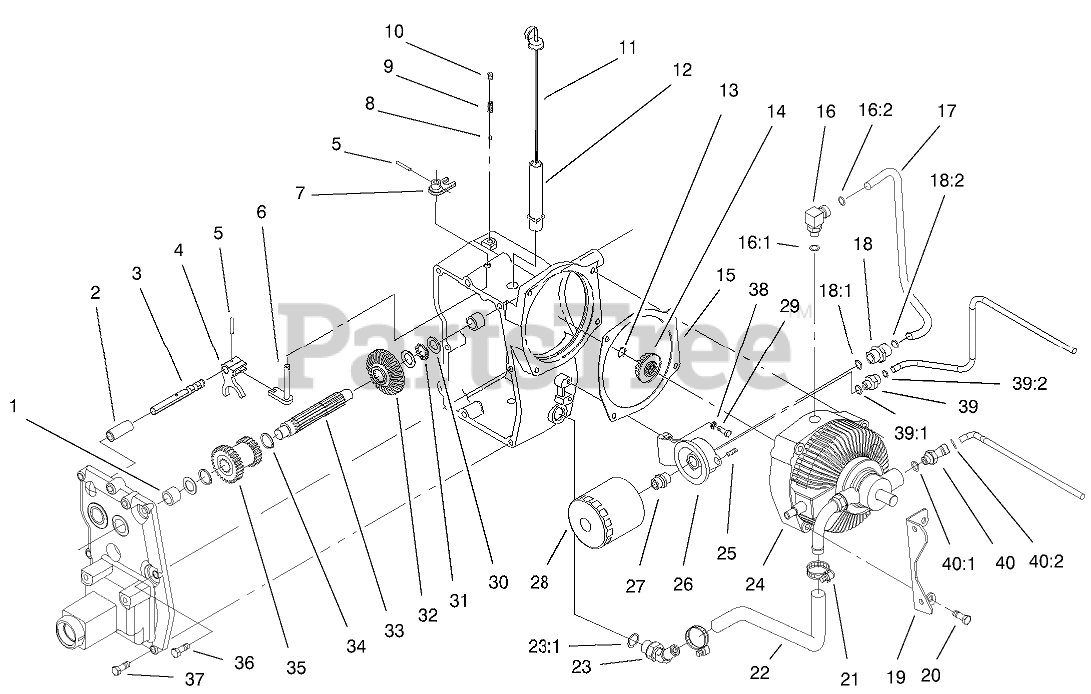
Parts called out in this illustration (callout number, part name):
1	BEARING-NEEDLE
2	TUBE-RAIL, SHIFTER
3	RAIL-SHIFT
4	FORK-HI / LO SHIFT
5	PIN-ROLL
6	ARM-SHIFTER
7	SHIFT-HI / LO
8	BALL-DETENT
9	SPRING-DETENT, SHIFT
10	SCREW-SET, HSH
11	DIPSTICK
12	TUBE-DIPSTICK
13	RING-SNAP, EXTERNAL
14	PINION-BEVEL
15	GASKET
16	FITTING -HYD, 90 DEGEE
16:1	O-RING
16:2	O-RING
17	TUBE-HYD
18	FITTING-STRAIGHT
18:1	O-RING
18:2	O-RING
19	PLATE-BRACKET, SUPPORT
20	SCREW-HH
21	CLAMP-DRIVE, WORM
22	HOSE-SUCTION
23	FITTING-HOSE
23:1	O-RING
24	TRANSMISSION-HYDRO
25	PLUG-PIPE
26	BASE-FILTER
27	FITTING
28	OIL FILTER ASM
29	SCREW-HH
30	WASHER-THRUST
31	BEARING-THRUST
32	GEAR-BEVEL
33	SHAFT-INPUT
34	RING-RETAINING
34	WASHER-FLAT
35	GEAR-HI / LO
36	SCREW-HH
37	SCREW-HH
38	WASHER-LOCK
39	FITTING-HYD. STRAIGHT
39:1	O-RING
39:2	O-RING
40	FITTING-HYD, 45 DEGREE
40:1	O-RING
40:2	O-RING
